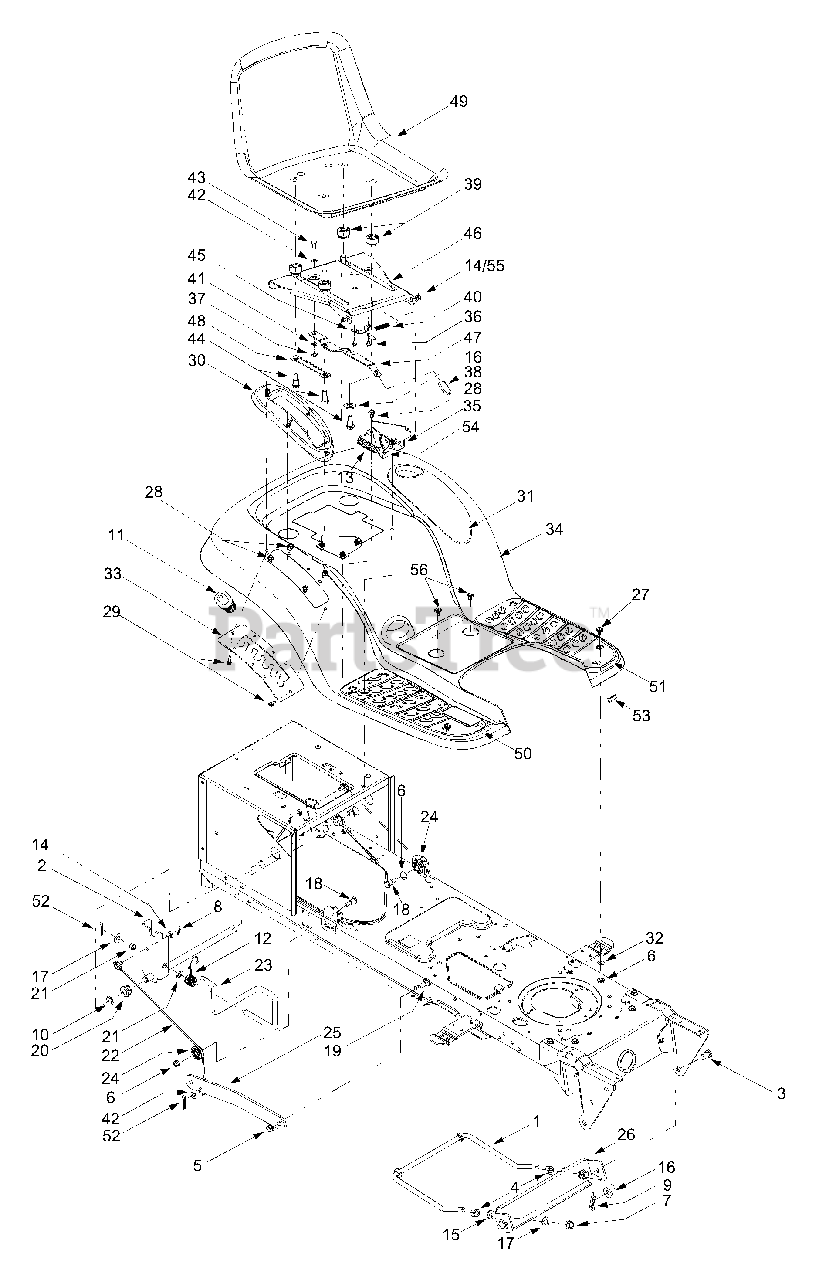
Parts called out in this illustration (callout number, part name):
1	Deck Stabilizer Rod
3	Clevis Pin, .5 x .78
4	Lock Nut, 1/2-13
5	Lock Nut, 3/8-16
6	Lock Nut, 5/16-18
7	Hex Nut, 1/2-13
8	Internal Cotter Pin
9	Internal Cotter Pin
12	Torsion Spring
13	Extension Spring, .872 x 3.4
14	Flat Washer, 5/16
15	Lock Washer, 1/2
16	Flat Washer, .31 x 1.062 x .134
17	Flat Washer, .51 x 1.12 x .06
18	Hex Cap Screw, 5/16-18 x .62
19	Shoulder Screw, 3/8-16
20	Hex Flange Bearing
21	Snap Flange Bearing
22	Lift Cable, 16.16
24	Roller Pulley
27	Self-tapping Screw 5/16-18 x 1.0
28	Self-Tapping Screw, 5/16-18 x .625
29	Self-Tapping Screw, 1/4-15 x .75
30	Lift Lever Cover
31	Cover w/ Cup Holder
32	Flat Washer, .349 x 1.0 x .063
36	Screw, #10-16 x .375
37	Hex Lock Nut, 1/4-20
38	Seat Adjuster Grip
40	Compression Spring, .41 x 1.5
41	Spring Washer, .265 x .562 x .025
42	Flat Washer, .344 x .62 x .03
43	Shoulder Screw, .340 x .285,1/4-20
44	Shoulder Screw, .50 x .925, 3/8-16
48	Seat Adjustment Selector
49	Medium Back Seat, Black
54	Seat Lift Bracket
56	Self-Tapping Screw 1/4-20 x 0.5"
